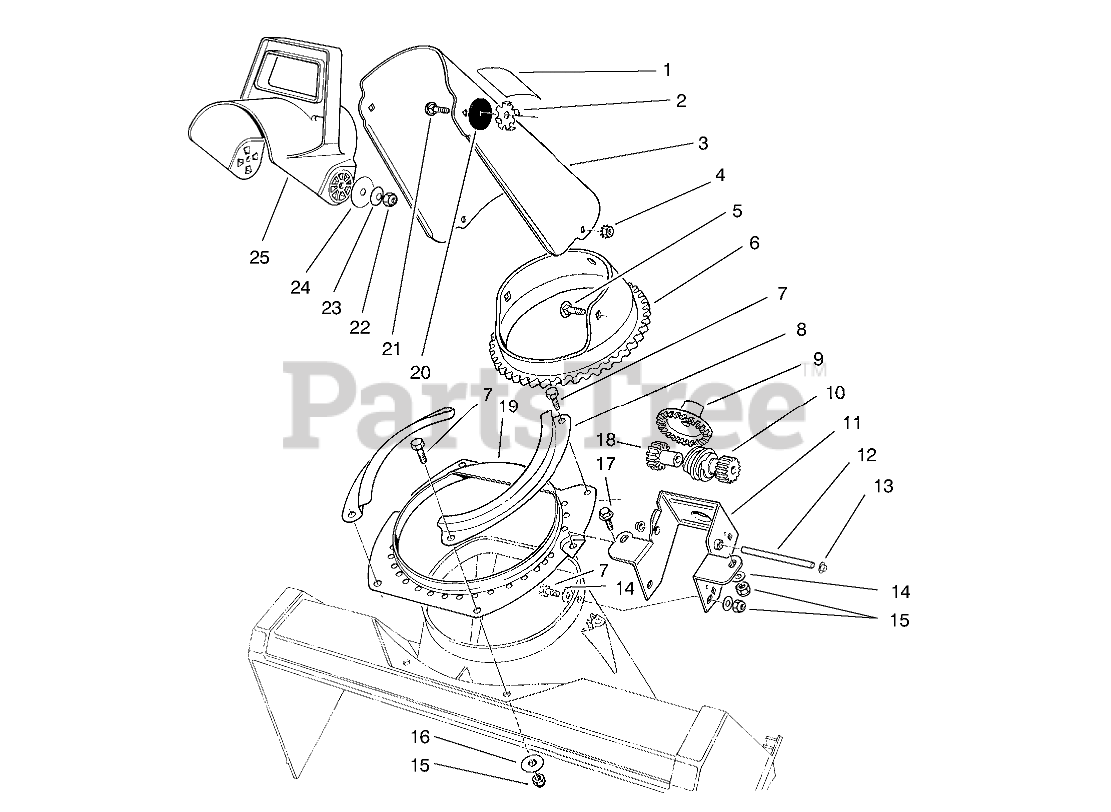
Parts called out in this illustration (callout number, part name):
1	DECAL - DANGER DISCHARGE
2	PLATE-FRICTION
3	Chute-Discharge (Model No. 38435)(Incl. Ref. #1)
4	NUT-KEPS
5	SCREW-CARR
6	RING-GEAR, CHUTE
7	SCREW-HH
8	Retainer-Chute Ring
9	GEAR-FACE
10	GEAR-SPUR/WORM
11	Bracket-Chute Gear
12	SHAFT-GEAR, WORM
13	NUT-PUSH
14	WASHER-FLAT
15	NUT-LOCK, NI
16	WASHER-FLAT
17	SCREW-PLASTITE
18	GEAR-SPUR, SPACER
19	Ring-Chute Support
20	WASHER-RUBBER
21	SCREW-CARR
22	NUT-LOCK, NI
23	WASHER-BELLEVILLE
24	WASHER-FLAT
25	CHUTE-DEFLECTOR
